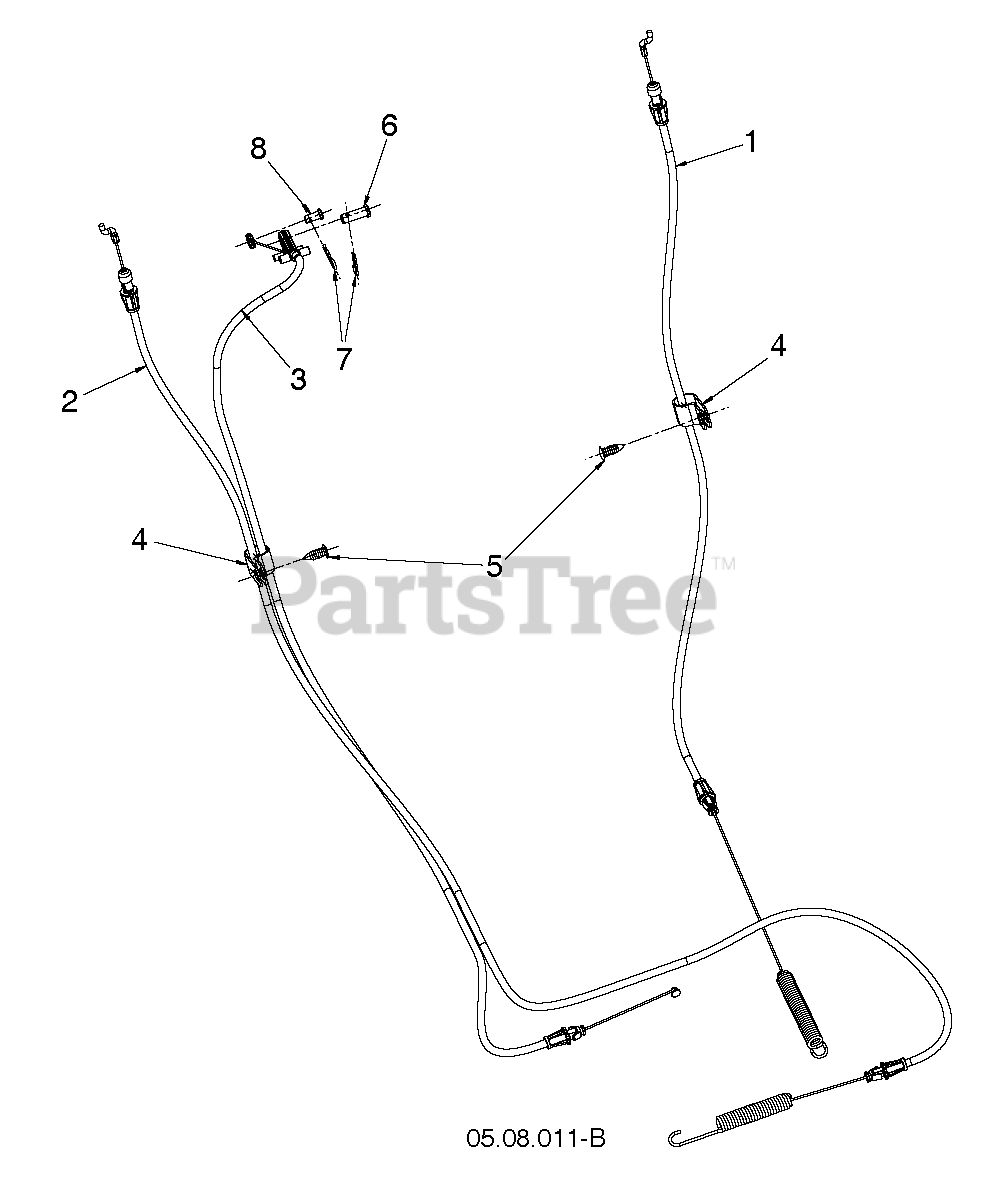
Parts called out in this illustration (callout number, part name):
1	CABLE.CONTROL.DRIVE.16
2	CABLE.CONTROL.AUGER
3	CABLE.CONTROL.SPEED.DSST.OPP
4	CLIP.CABLE.BLK
5	FASTENER.PUSH.O.250X0.783
6	PIN CLEVIS 5/16X.875
7	HAIRPIN.SOFT.ZINC.059X1.125
8	PIN CLEVIS .25 X .31
